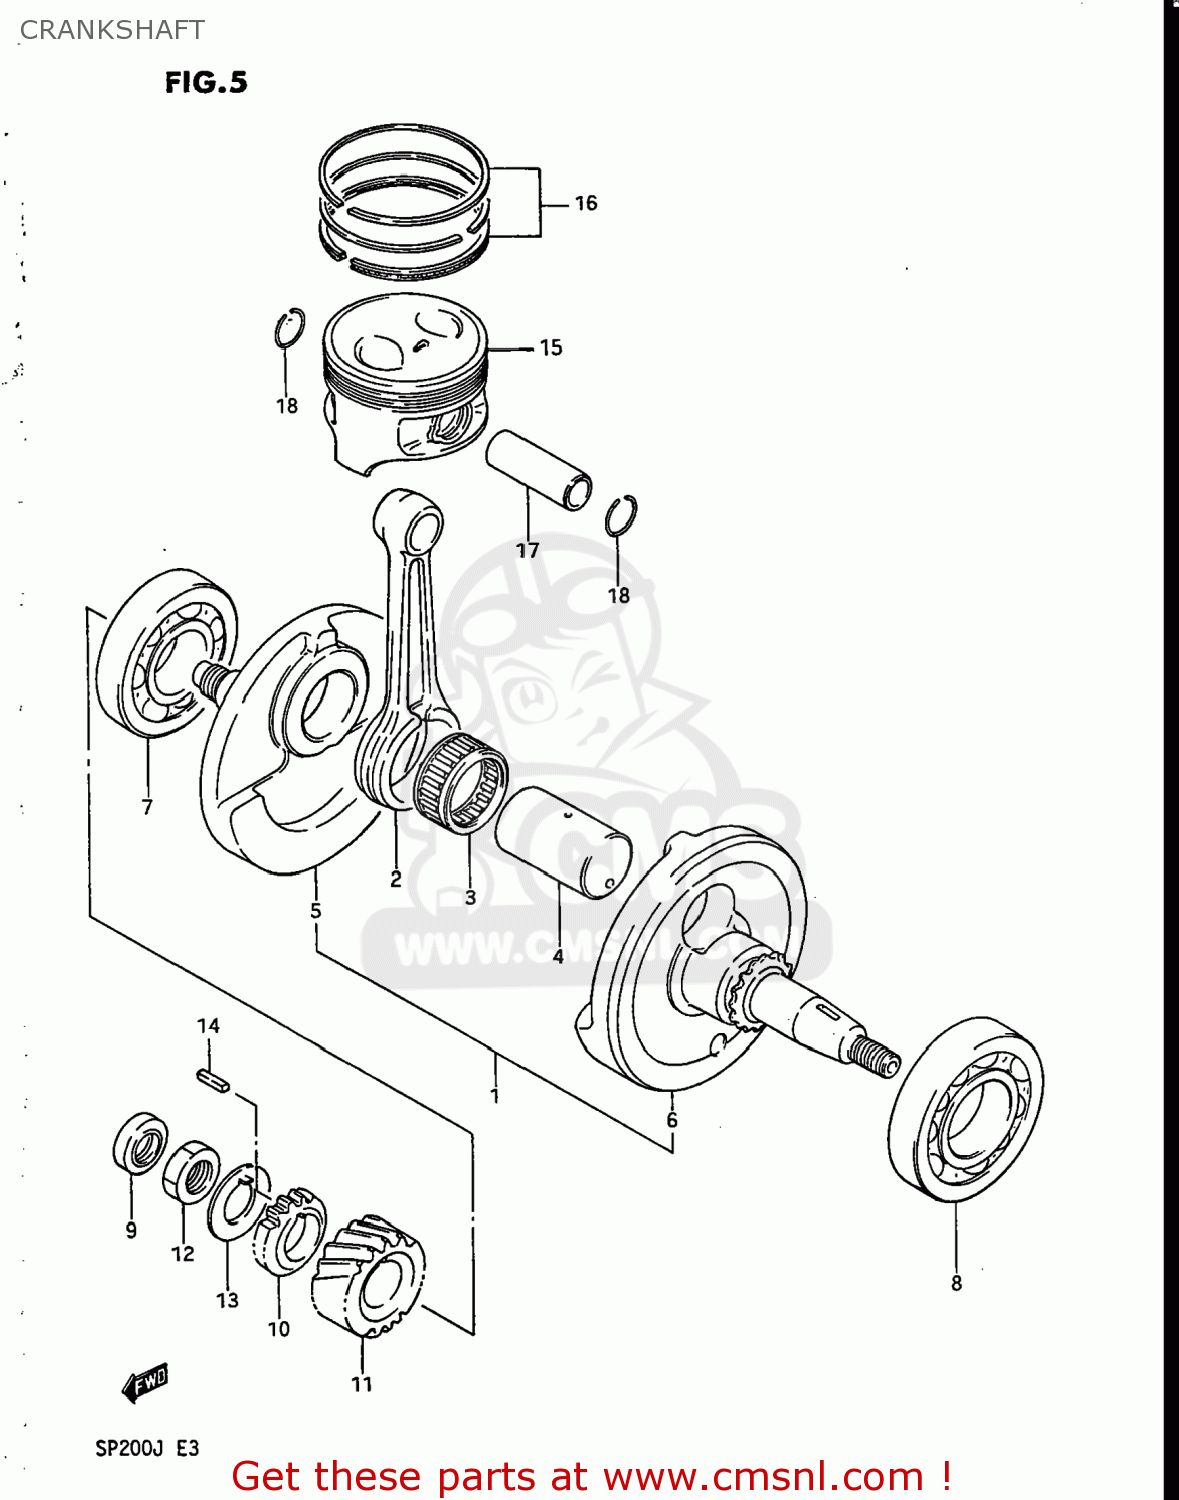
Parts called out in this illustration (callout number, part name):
1	CRANKSHAFT ASSEMBLY
2	CONNECTING ROD
3	BEARING(31X38X18)
4	PIN,CRANK
5	CRANKSHAFT,R
6	CRANKSHAFT,LEFT
7	BEARING(28X68X18)
8	BEARING
9	OIL SEAL
10	GEAR,OIL PUMP DRIVE(NT:15)
11	GEAR,PRIMARY DRIVE (NT:
12	NUT
13	WASHER
14	KEY
15	PISTON
16	RING SET,PISTON
17	PIN,PISTON
18	CIRCLIP
